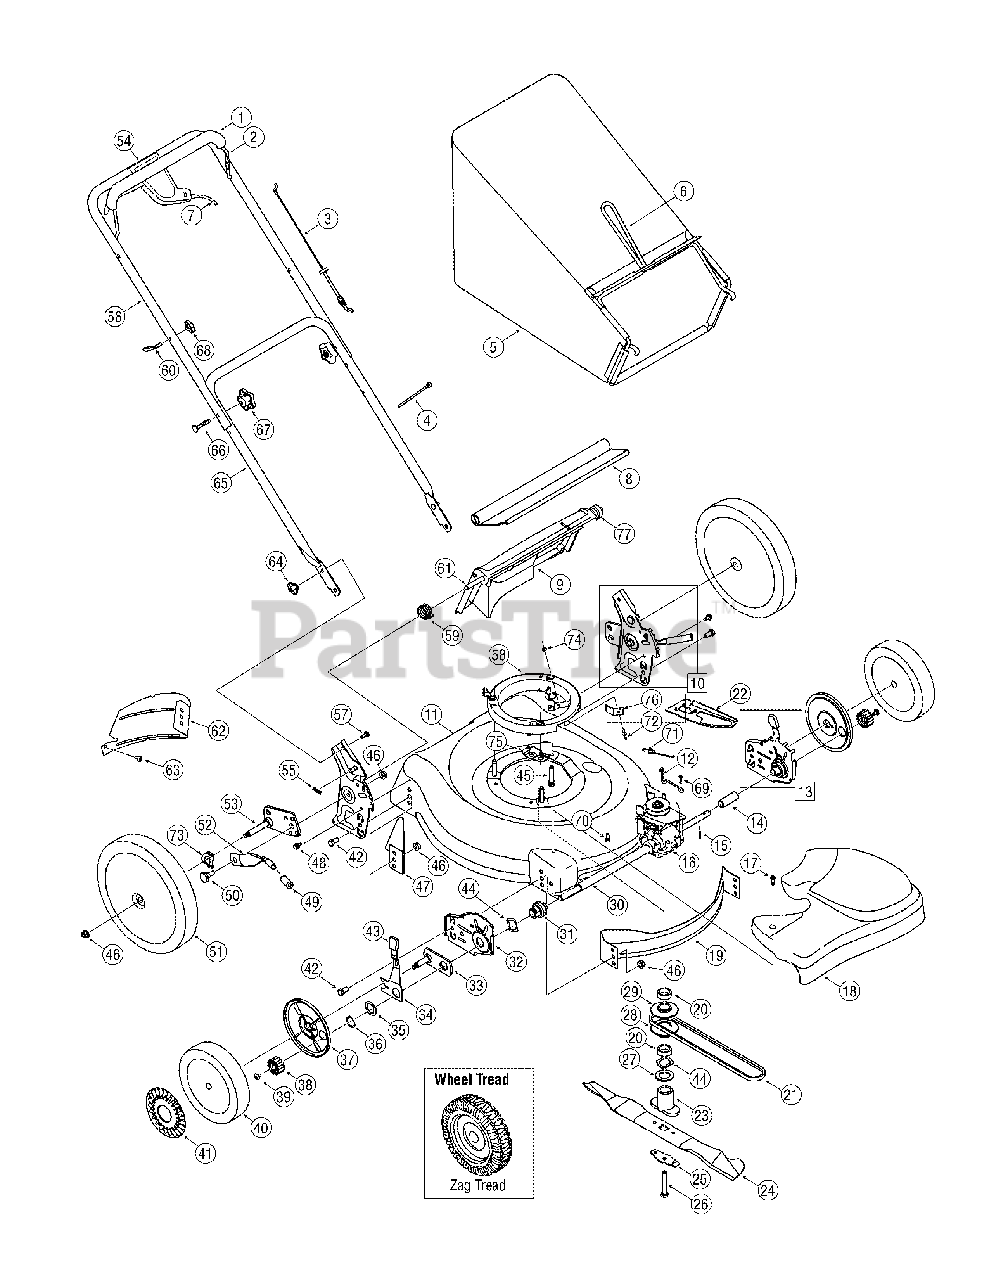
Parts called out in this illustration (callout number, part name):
1	Bail Cover
2	Blade Control
3	Control Cable 37.25-inch
4	Cable Tie
5	Grass Bag Assembly
7	Variable Speed Cable
8	Trailshield
9	Rear Door
10	Height Adj. Bracket Assy - LH
10	Height Adj. Bracket Assy - RH
11	21-inch Deck
12	Extension Spring
13	Front Height Adj. Assy - LH
13	Front Height Adj. Assy - RH
14	Sleeve Spacer .52 ID x 1.8 Lg
15	Dowel Pin
16	Transmission
17	Shoulder Screw
18	Deck Cover
19	Front Baffle
20	Spacer, Sleeve
21	V-Type Belt
22	Cable Mount Bracket
23	Blade Adapter
24	21-inch Mulching Blade
25	Blade Bell Support
26	Screw 3/8-24 x 2.5
27	Flat Washer, 1.031 x 1.620 x .095
28	Key Half Pulley
29	Upper Half Pulley
30	Sleeve Spacer, .52 Lg x 9.10
31	Front Bearing Assembly
32	Adjustment Plate RH
32	Adjustment Plate LH
33	Pivot Plate Assembly
34	Spring Lever RH
34	Spring Lever LH
35	Flat Washer 1.01 x 1.5 x .035
36	Snap Ring
37	Wheel Cover
38	Spur Gear 14T RH
38	Spur Gear 14T LH
39	Screw 1/4-20 x .39
40	Front Wheel 8 x 2.125 Zag
41	Hubcap
42	Screw 3/8-16 x .75
43	Knob
44	Wave Washer 1.5 x 1 x .029
45	Screw TT 3/8-16 x 1.875
46	Flange Lock Nut 3/8-16
47	Rear RH Baffle
48	Screw TT 1/4-20 x .625
49	Foam Grip
50	Shoulder Screw
51	Rear Wheel 14 x 2.125 Idle Zag
52	Spring Lever
53	Pivot Arm Assembly RH
53	Pivot Arm Assembly LH
54	Speed Control Assembly
55	Hairpin Clip
56	Upper Handle
57	Screw 1/4-20 x .75
58	Engine Spacer
59	Torsion Spring RH
60	Eye Bolt
61	Pivot Rod
62	Rear Baffle LH
63	Screw AB 1/4-14 x .625
64	Wing Nut
65	Lower Handle
66	Carriage Bolt 5/16-18 x 2
67	Star Knob
68	Handle Knob
69	Torx Screw
70	Screw, 1/4-14 x .625
71	Belt Keeper Wire
72	Rivet, Pop
73	Spring Washer, .500 x 1.00 x .022
74	Washer, Flat, .203 x .403 x .040
75	Bracket, Belt Keeper
76	Bracket, Belt Keeper
77	Torsion Spring LH
